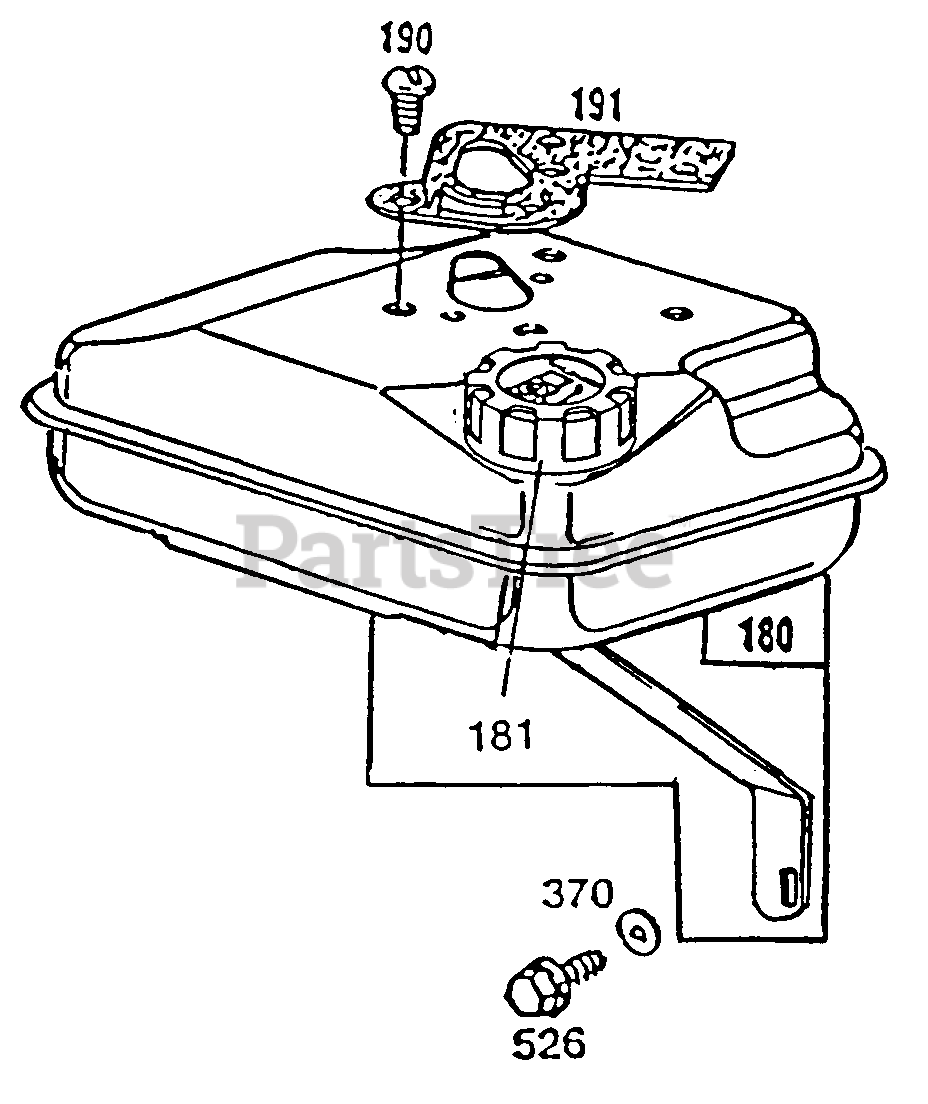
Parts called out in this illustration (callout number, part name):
180	Tank Ass'y.--Fuel
181	Cap--Fuel Tank
190	Screw--Fuel Tank Mounting
191	Gasket--Fuel Tank
370	Washer--Plain
526	Screw--Tank Bracket Mounting
